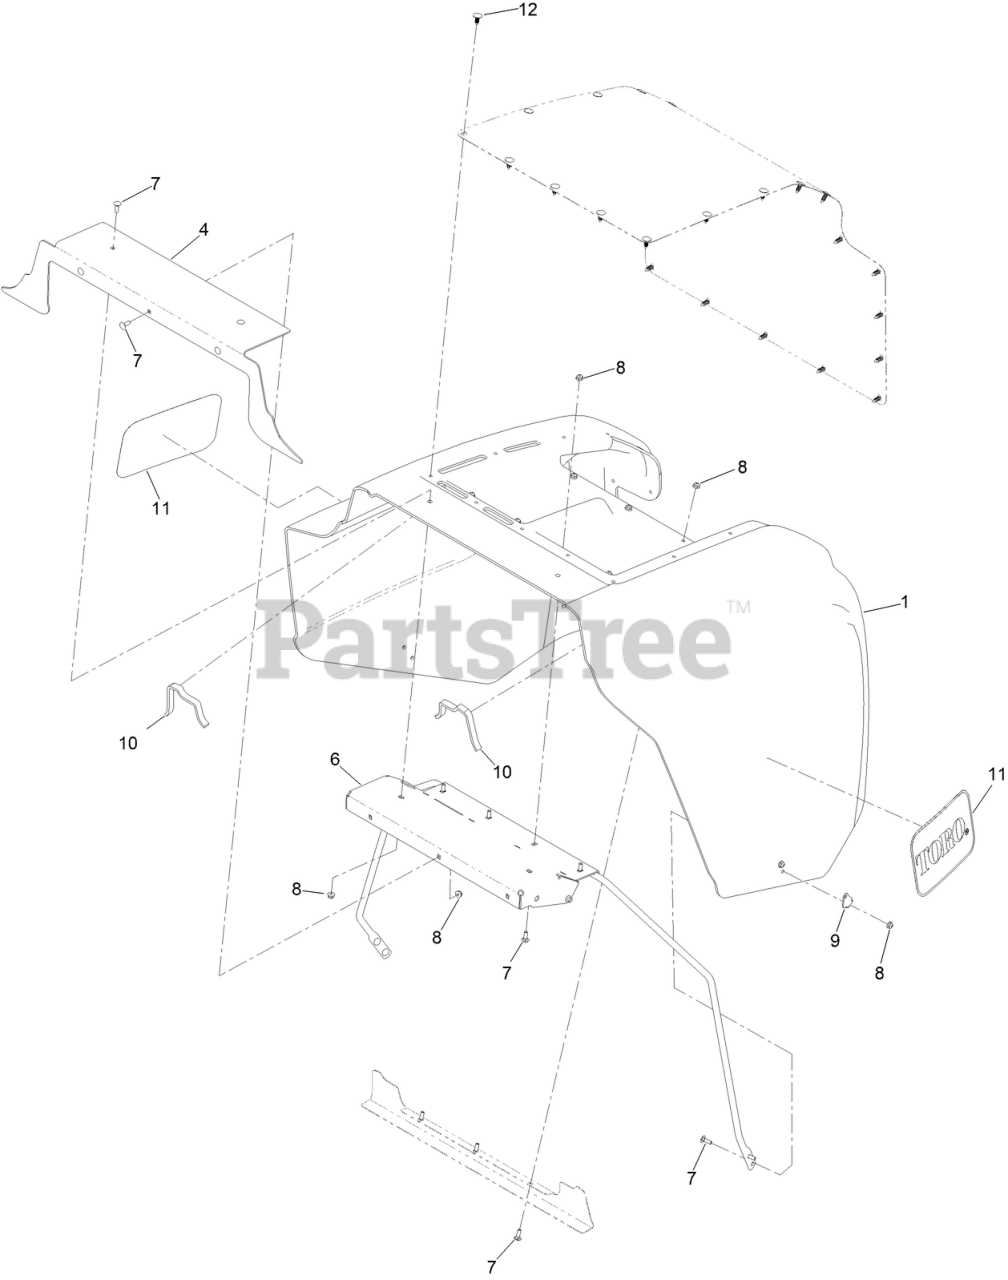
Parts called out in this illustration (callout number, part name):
4	BRACKET-HOOD BLOCK OFF
6	HOOD SUPPORT ASM [BLACK]
7	BOLT-CARR
8	NUT-HF
9	LATCH, KEEPER
10	SEAL-FOAM
11	DECAL
12	PLUG-PLASTIC
